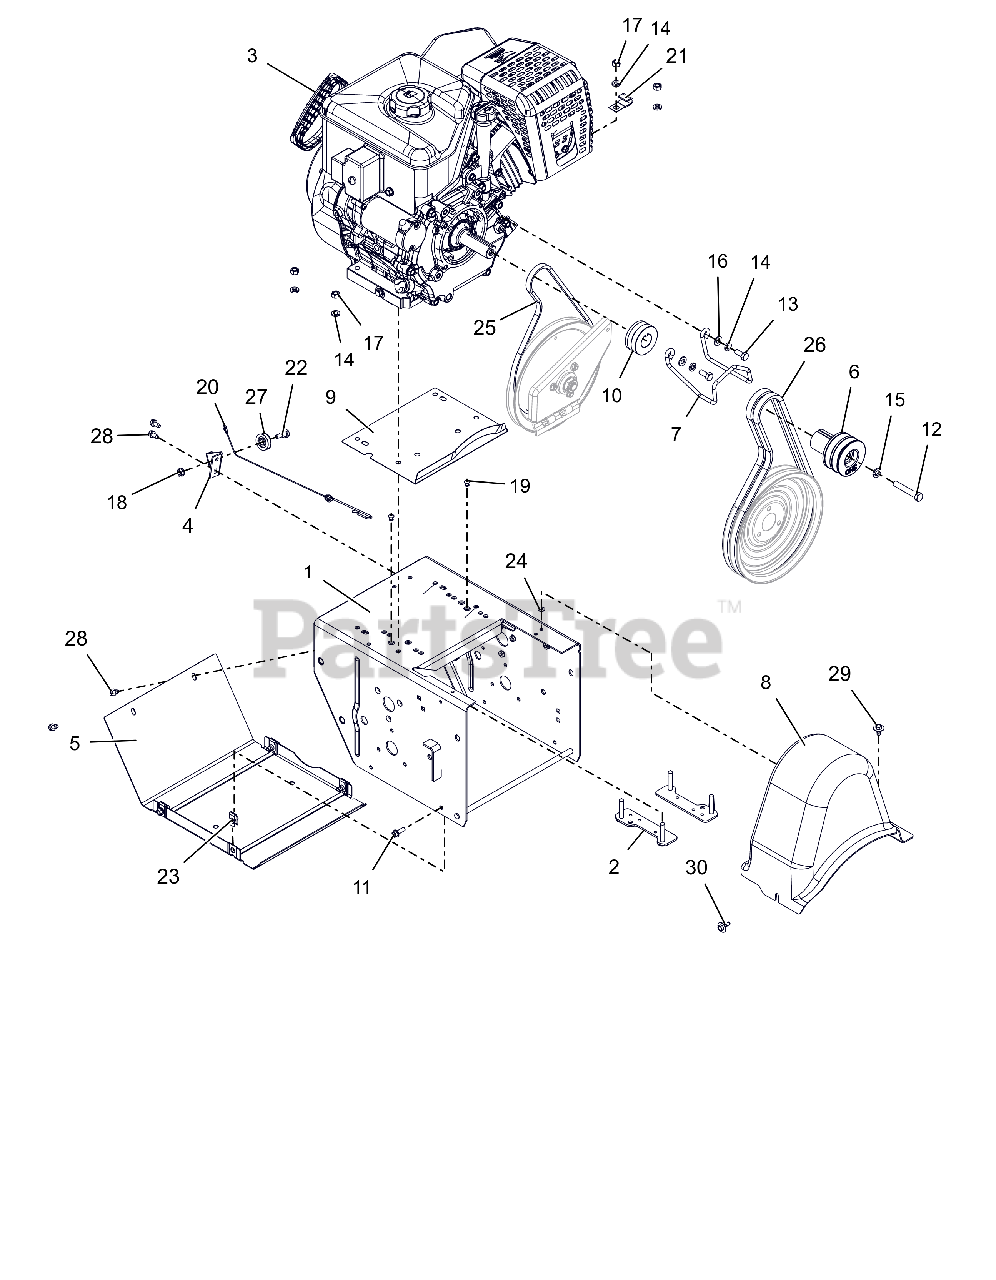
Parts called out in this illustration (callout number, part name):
1	FRAME, MAIN-DELUXE(WELDMENT)
2	STRAP, BOLT-LARGE
3	ENGINE,EFI369 GEN3 120V/60W
4	BRACKET, CABLE PULLEY
5	COVER, BOTTOM
6	SHEAVE,ATTACHMENT-SHO 2 GRV
7	FINGER, BELT
8	COVER, BELT-LARGE
9	BAFFLE, WATER - LARGE BLOCK
10	SHEAVE, DRIVE
11	BLT-HEX .25-20X.75 HWH YZ GR5
12	BLT-HEX .38-24X2.25 YWZC GR5
13	BLT-HEX .31-24X.75 YWZC GR5
14	WSHR-LK .312X.097 HVY YWZC
15	@WSHR-LK .38X.094 REG YWZC
16	@WSHR-FL-STL.344X.688X.065YWZC
17	@NUT-HEX .31-18 YWZC
18	@NUT-LK-TOP-FLG .25-20 YWZC
19	RVT-POP .187 YZ
20	CABLE, LOWER TRACTION,SS & PRO
21	J-CLAMP
22	BOLT, SHLDR-.375X.375X.25-20
23	NUT-RTNR .25-20X.56
24	NUT-PUSH .25X.50 O.D.
25	V-BELT, 3L-WRAPPED
26	V-BELT, HA-RAW EDGE (SET)
27	PULLEY, CABLE
28	SCR-TAP .25-20X.50 HWH TR YWZ
29	SCR-TAP .25-20X.50 LGHWH TR YZ
30	SCR-TAP .25-20X.5 CAPTIVE
